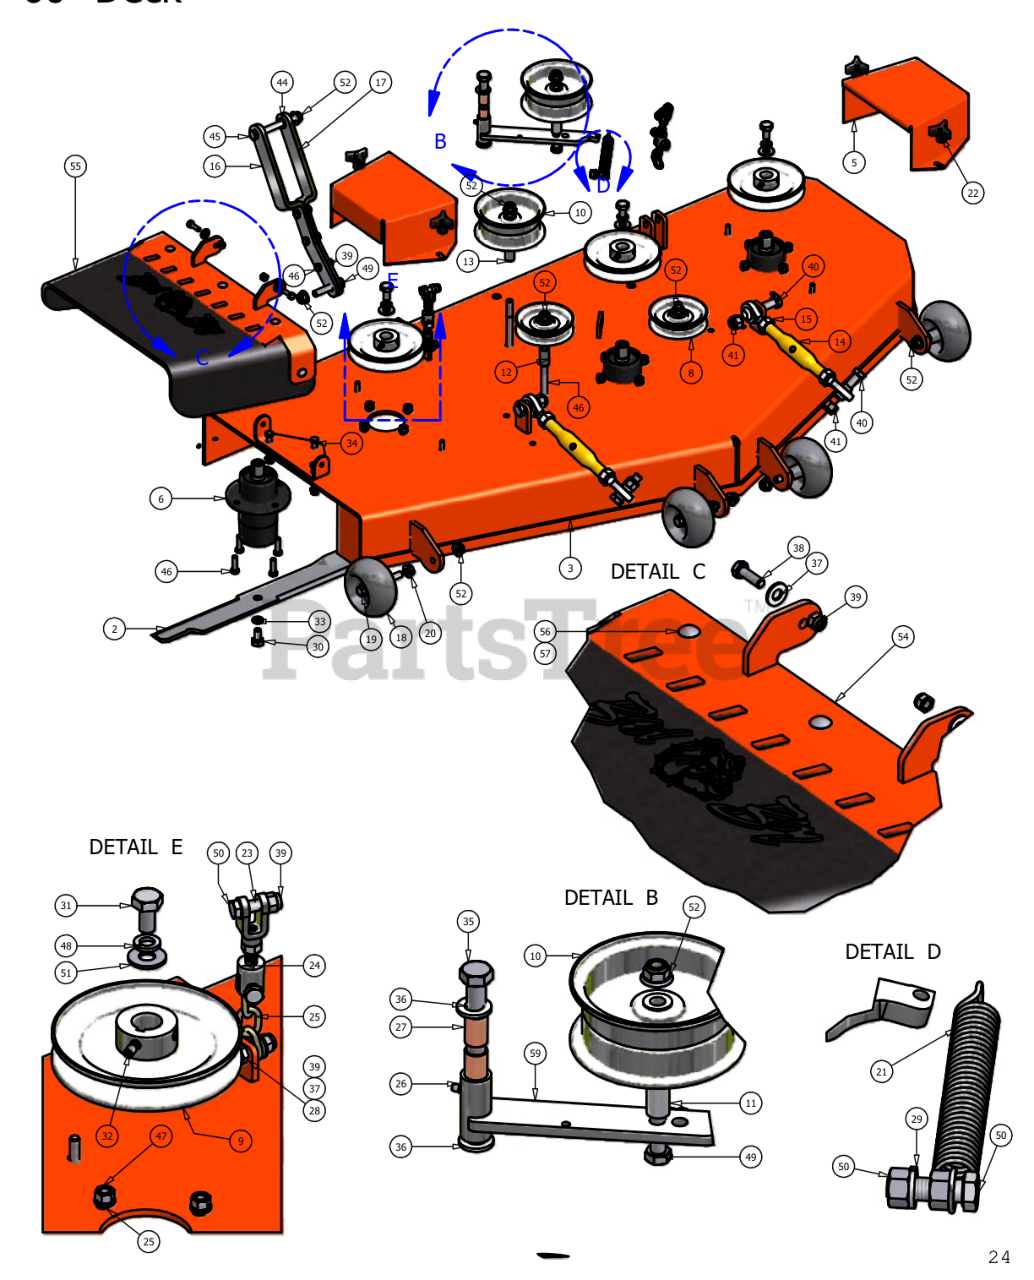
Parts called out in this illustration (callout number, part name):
1	60" Deck Belt
2	60" Fusion Blade
4	Dischage Chute Hander
5	Pulley Guard
7	Deck Idler Pully
8	4 3/4" Idler Pulley
9	6 1/4" Drive Pulley
10	5 3/4" Flat Idler Pulley
11	1 1/4" Pulley Spacer
12	Pup Pulley Spacer
13	1 3/4" Pulley Spacer
14	Turnbuckle
15	3/4" Left Hand Nut
16	Deck Support Arm (Left)
17	Deck Support Arm(Right)
18	Anti-Scalp Roller
19	1/2"x4" Bolt (Grade8)
20	1/2" Flange Nut
21	Deck Idler Spring
22	5/16" Knob
23	Female Yoke
26	Grease Fitting
27	5/8" ID x 1 1/8" Brass Bushing
28	3/8" x 1" Hex Bolt
29	5/8" x 2" Fine Threaded Bolt
30	3/8" Lock Washer
31	1/2" x 1 1/2" Bolt (Fine Threaded)
32	3/8" Set Screw
33	5/8" Lock Washer
34	3/8" x 3/4" Hex Bolt
35	5/8" x 4" Hex Bolt
36	.635 ID Plastic Washer
37	.360 ID Plastic Washer
38	5/16" x 1" Hex Bolt
39	5/16" Nylock Nut
40	5/8" x 2 1/2" Hex Bolt
41	5/8" STD NC Nylock Nut
42	1/2" x 3 1/2" Bolt
44	1/2" Brass Washer
45	1/2" x 4 1/2" Bolt
46	3/8" x 1 1/4" Hex Bolt
47	3/8" Hex Nut
48	1/2" Lock Washer
49	1/2" x 2 1/2" Hex Bolt
50	3/8" x 1 1/2" Hex Bolt
51	1/2" Cupped Washer
52	1/2" Flange Lock Nut
53	2007 Lower Hanger
54	2007 Hanger Plate
55	Rubber Side Discharge
56	5/16" x 1 1/2" Carriage Bolt
57	5/16" Nylock Flange Nut
